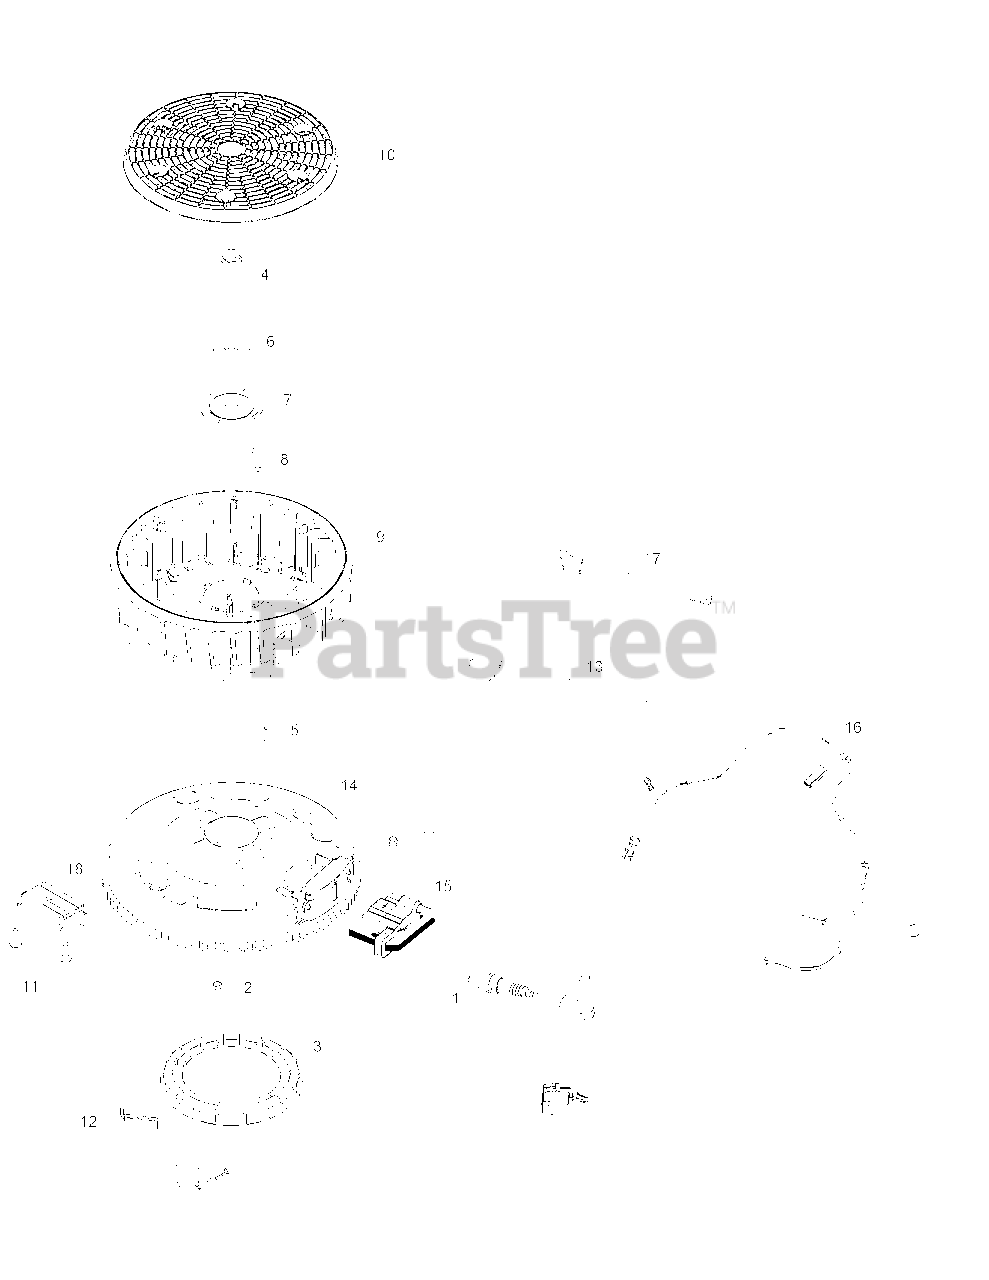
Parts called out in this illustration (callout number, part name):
2	Thread Forming Screw
3	15 Amp Stator Kit
4	Hex Flange Screw
7	Fan Mounting Plate
8	Flywheel Fan Retainer
11	Thread Forming Screw
14	Flywheel Assembly
15	Ignition Module
16	Wiring Harness
18	Rectifier Regulator
